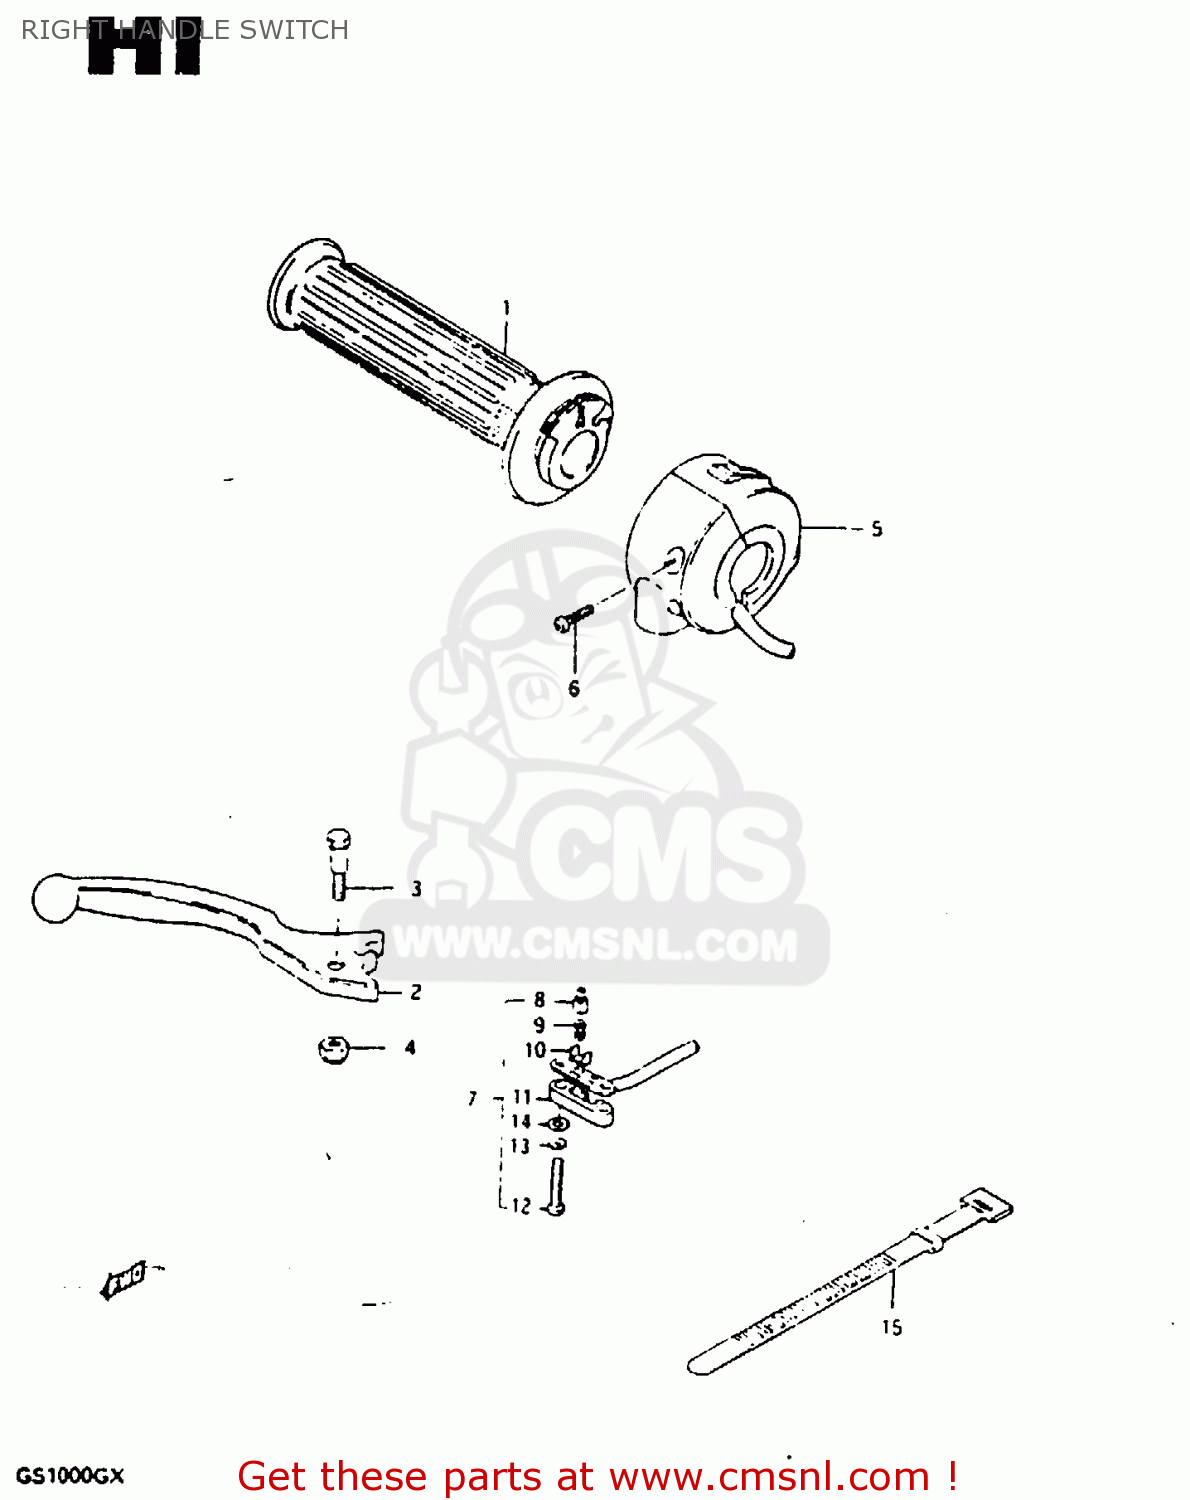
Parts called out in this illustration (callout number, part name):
1	GRIP,THROTTLE
2	LEVER,BRAKE
3	BOLT
4	NUT 6MM
5	SWITCH ASSEMBLY,HANDLE,RIGHT
6	SCREW
15	CLAMP(L:120)
